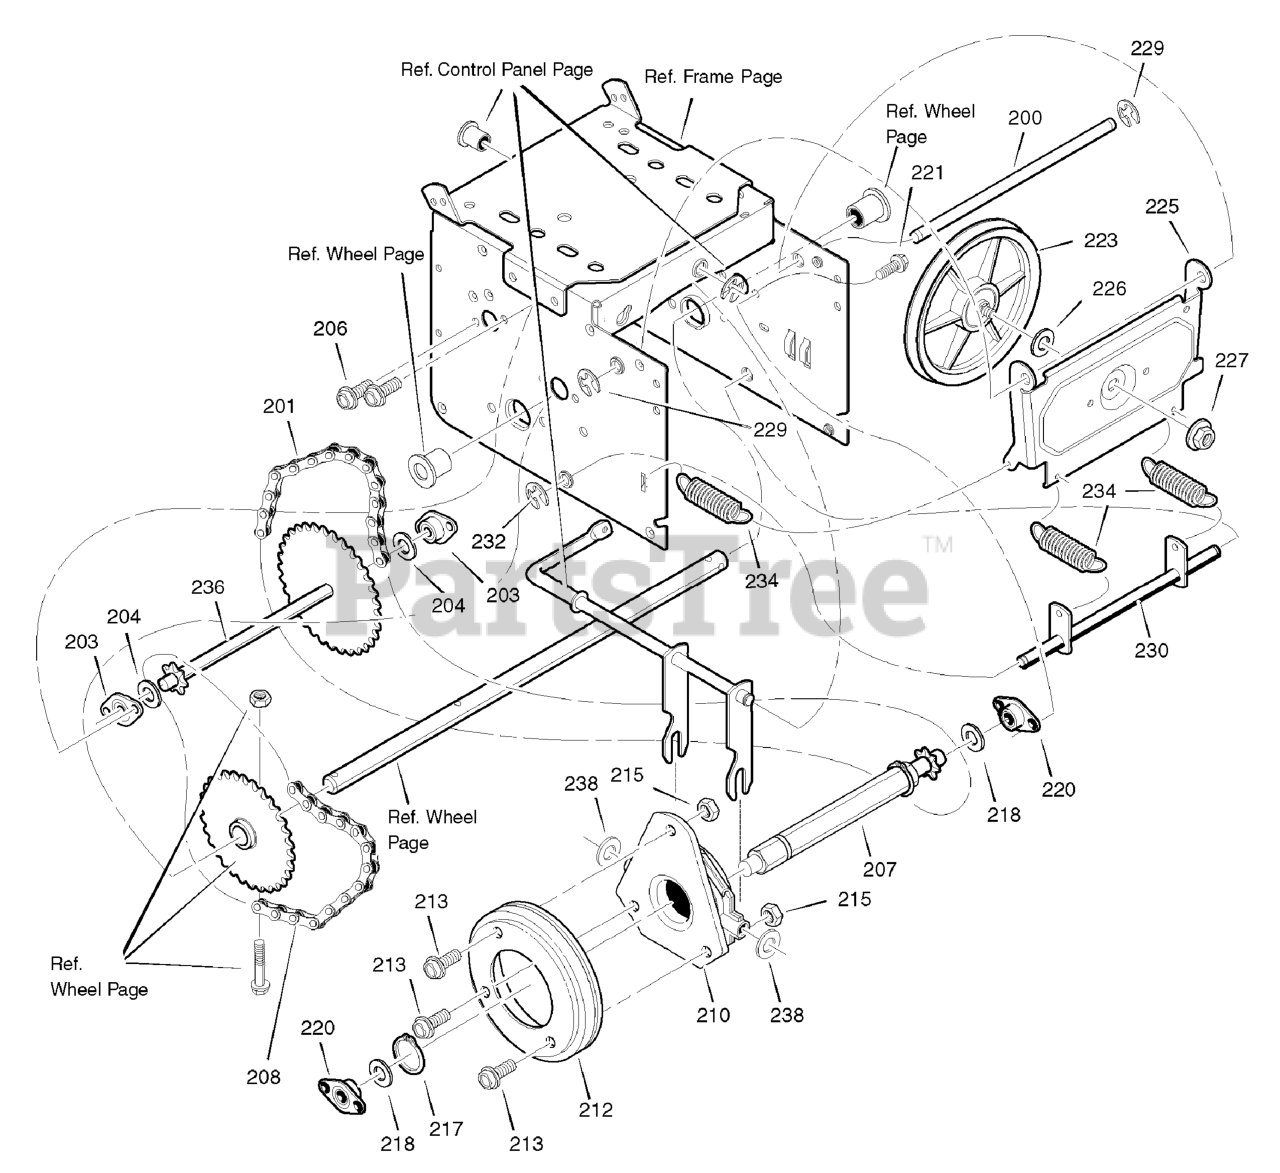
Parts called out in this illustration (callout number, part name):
200	LF AXLE, SWING PLATE YZ
201	CHAIN, ROLLER #420 X 19.00
203	BEARING AND RETAINER, ASSEMBLY
206	SCREW, TAP 5/16-18 X .5
207	HEX SHAFT ASSEMBLY
208	CHAIN, ROLLER #420 X 18.00 LG
210	BEARING, TRUNION CLUTCH R
212	WHEEL, FRICTION DISC
215	NUT, KEPS HEX 1/4-20
217	RING, RETEXT
220	BEARING AND RETAINER ASSEMBLY
221	SCREW, TAP 5/16-18 X 0.5
223	ASSEMBLY, FRICTION PULLEY
225	LF PLATE, SWINGING YZ
226	SPACER, FRICTION PULLEY
227	NUT, FLANGE LOCK 3/8-24
229	RETAINER, RING
230	SPRING LINK YZ LF ASSEMBLY
232	RETAINER, RING
234	SPRING, EXTENSION
236	INTERMED SPROCKET 33T/7
238	WASHER, FLAT
